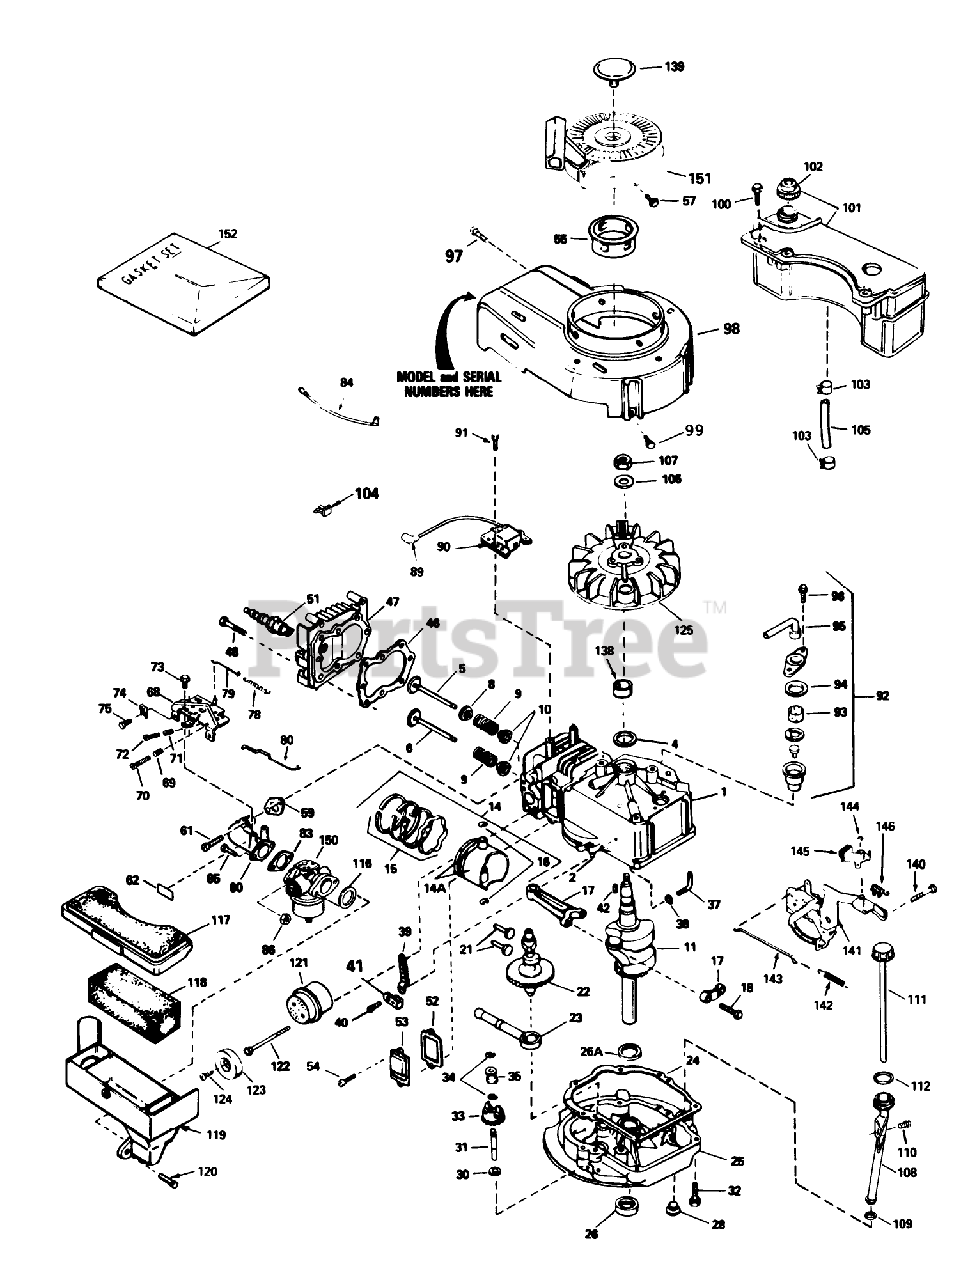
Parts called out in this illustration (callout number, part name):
1	Cylinder Assy. (Incl. #24)
2	Pin-Dowel
4	Seal-Oil
5	Valve, Intake (Std.) (Incl. Ref. #40)
5	Valve, Intake (1/32" oversize)(Incl. No. 40)
6	Valve, Exhaust (Std.)(Incl. No. 40)
6	Valve, Intake (1/32" oversize)(Incl. No. 40)
8	Seal Assy., Intake
9	Spring-Valve
10	Cap-Valve, Spring
11	Crankshaft
14	Piston-Pin Ring Assy. (Std.)(Incl. Ref. #16A, 17 18)
14	Piston-Pin Ring Assembly (.010 oversize)(Incl. Ref. #16A, 17 18)
14	Piston, Pin Ring Assy. (.020 Oversize)(Incl. Ref. #13A, 14, 15)
14A	Piston Pin Assy. (Std.)(Incl. Ref. #14)
14A	Piston Pin Assembly (.010 oversize)(Incl. Ref. #18)
14A	Piston Pin Assy. (.020 Oversize) (Incl. Ref. #14)
15	Ring Set-Piston (Std.)
15	Ring Set, Piston(.0100versize)
15	Ring Set (.020" OS)
16	Ring-Retaining, Piston Pin
17	Rod Assy., Connecting (Incl. Ref. #17)
18	Bolt-Rod, Connecting
21	Lifter-Valve
22	Camshaft(Mech.Comp. Release)
23	Oil Pump ASM
24	Gasket
25	Flange-Mounting (Incl. Ref. #26, 27 39)
26	Seal-Oil
26A	Washer-Thrust
28	Plug Oil Drain
30	Washer-Flat
31	Shaft-Governor
32	Screw (1/4-20 x 1-1/4)
33	Governor Gear ASM
34	Ring-Retaining
35	Spool-Governor
37	Rod, Governor (Incl. No. 36)
38	Washer-Flat
39	Governor Lever
40	Screw
41	Clamp-Lever, Governor
42	Key-Flywheel
46	63573 GIL 42 SNWTHW
47	Head-Cylinder
48	Screw (5/16-18x1-1/2)
51	Spark Plug-Resistor (R J19 L M)
52	Gasket-Breather
53	Cover-Valve
54	Screw
55	Hub-Starter
57	Screw, Hex Hd.
59	Gasket-Intake
60	Pipe-Intake (Incl. Ref. #59)
61	Screw (1/4-20 x 1)
62	Decal-Primer
68	Control Assy.-Remote Speed (Incl. Ref. #69 thru 72 76)
69	61709/GIL1515A/95-5
70	Screw
71	Spring-Compression
72	Screw
73	Screw (10-24 x 9/16)
74	Conduit
75	Screw (10-32 x 3/8)
78	Spring Governor
79	2035A67 ADD.ASSEMBL
80	Link-Throttle
83	Gasket
84	Ground Wire
86	Nut and Lock Washer (1/4-28)
89	Cover-Spark Plug
90	Solid State
91	Screw
92	Breather Assy. (Incl. Ref. #46 thru 51)
93	Element-Breather
94	Gasket-Breather
95	Tube, Breaker
96	Screw (10-24 x 9/16)
97	Screw (10-24 x 9/16)
98	Housing-Blower
99	Screw (1/4-20 x 1/2)
100	Screw (10-32 x 35/64)
101	Tank Assembly-Fuel (Incl. Ref. #102)
102	Cap-Fuel
103	Clamp-Line, Fuel
104	Clip-Wire
105	Line-Fuel
106	Washer-Belleville
107	Nut-Flywheel
108	Oil Fill Tube
109	Gasket
110	Screw (10-32 x 1/2)
111	Dipstick
112	O-Ring
116	Gasket-Cleaner, Air
117	Cover-Air Cleaner
118	Filter-Air Cleaner
119	Body Air cleaner
120	Screw
121	Muffler (Incl. Ref. #122)
122	Screw
123	Cover-Muffler
124	Screw (8-32 x 3/8)
125	Flywheel
138	Spacer
139	Plug Starter
140	Screw (1/4-20 x 3/8)
141	Bracket-S.E. Brake
142	Spring-Extension
143	Link-Control
144	Ring-Retaining
145	Lever-Brake
146	Terminal
150	Carburetor (Incl. Ref. #83)
151	Starter-Rewind
152	Gasket Set
